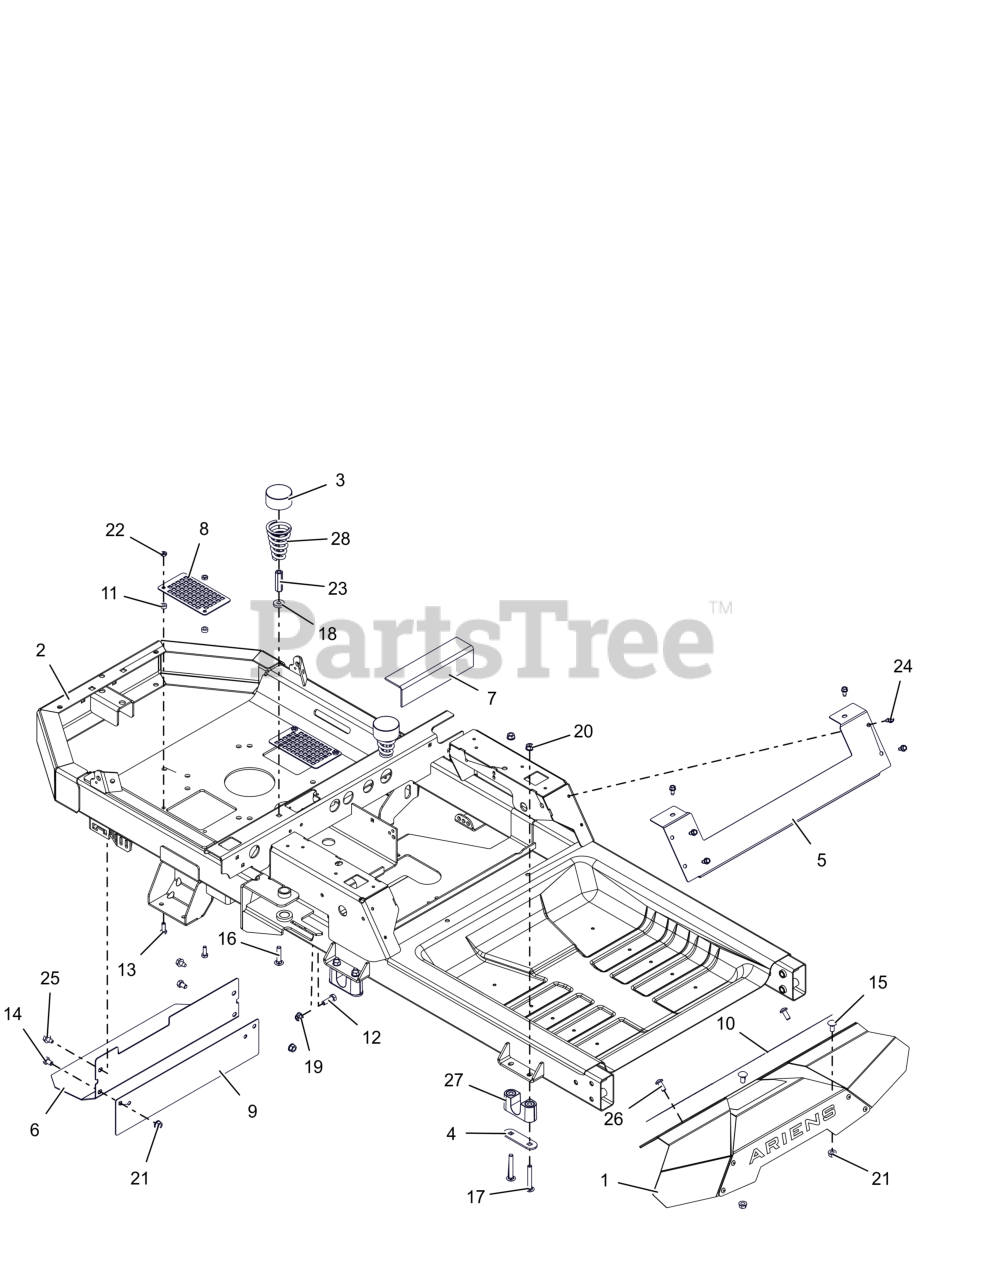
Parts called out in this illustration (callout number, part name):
1	KIT, IKON FOOT REST W/DECAL
2	WLDMT, FRAME IKON XD/ZTX & XL (ORANGE)
3	HUB CAP
4	PLATE, BEARING SUPPORT
5	PLATE, SEAT KICK
6	HEAT, SHIELD
7	PAD, RUBBER-TANK
8	GUARD, VENT
9	GUARD, REAR CLUTCH
10	GRIP TAPE, FOOT PLATE
11	BSHG-SLV .265X.500X.219
12	BLT,HEX .31-18X1.00 G5 ZCC
13	BLT, HEX .25-20X.75 G5 ZCC
14	BLT, HEX .31-18X.50 GR5 ZCC
15	BLT,RHSN .31-18X.75 G5 ZCC
16	BLT,RHSN .31-18X1.50 G5 ZCC
17	BLT, RHSSN.31-18X2.25 G5 ZCC
18	WSHR, FLT .328X.870X.179 ZCC
19	NUT,LK-NYL-FLG .31-18 G5ZC120
20	NUT,LK-CTR-FLG .31-18 GF ZCC
21	NUT-LK-TOP-FLG .312-18 GF ZCC
22	NUT-LK-CTR-JAM .250-20 GB ZCC
23	NUT, COUPLING .31-18X1.75 ZCC
24	SCR-TAP .25-20X.50 HWH ZCC
25	SCR,TAP .312-18X.50 HWH TR ZCC
26	SCR-RDHDSKTAP .31-18X.75 ZCC
27	BSHG, DECK LIFT PIVOT
28	SPRING, SEAT
